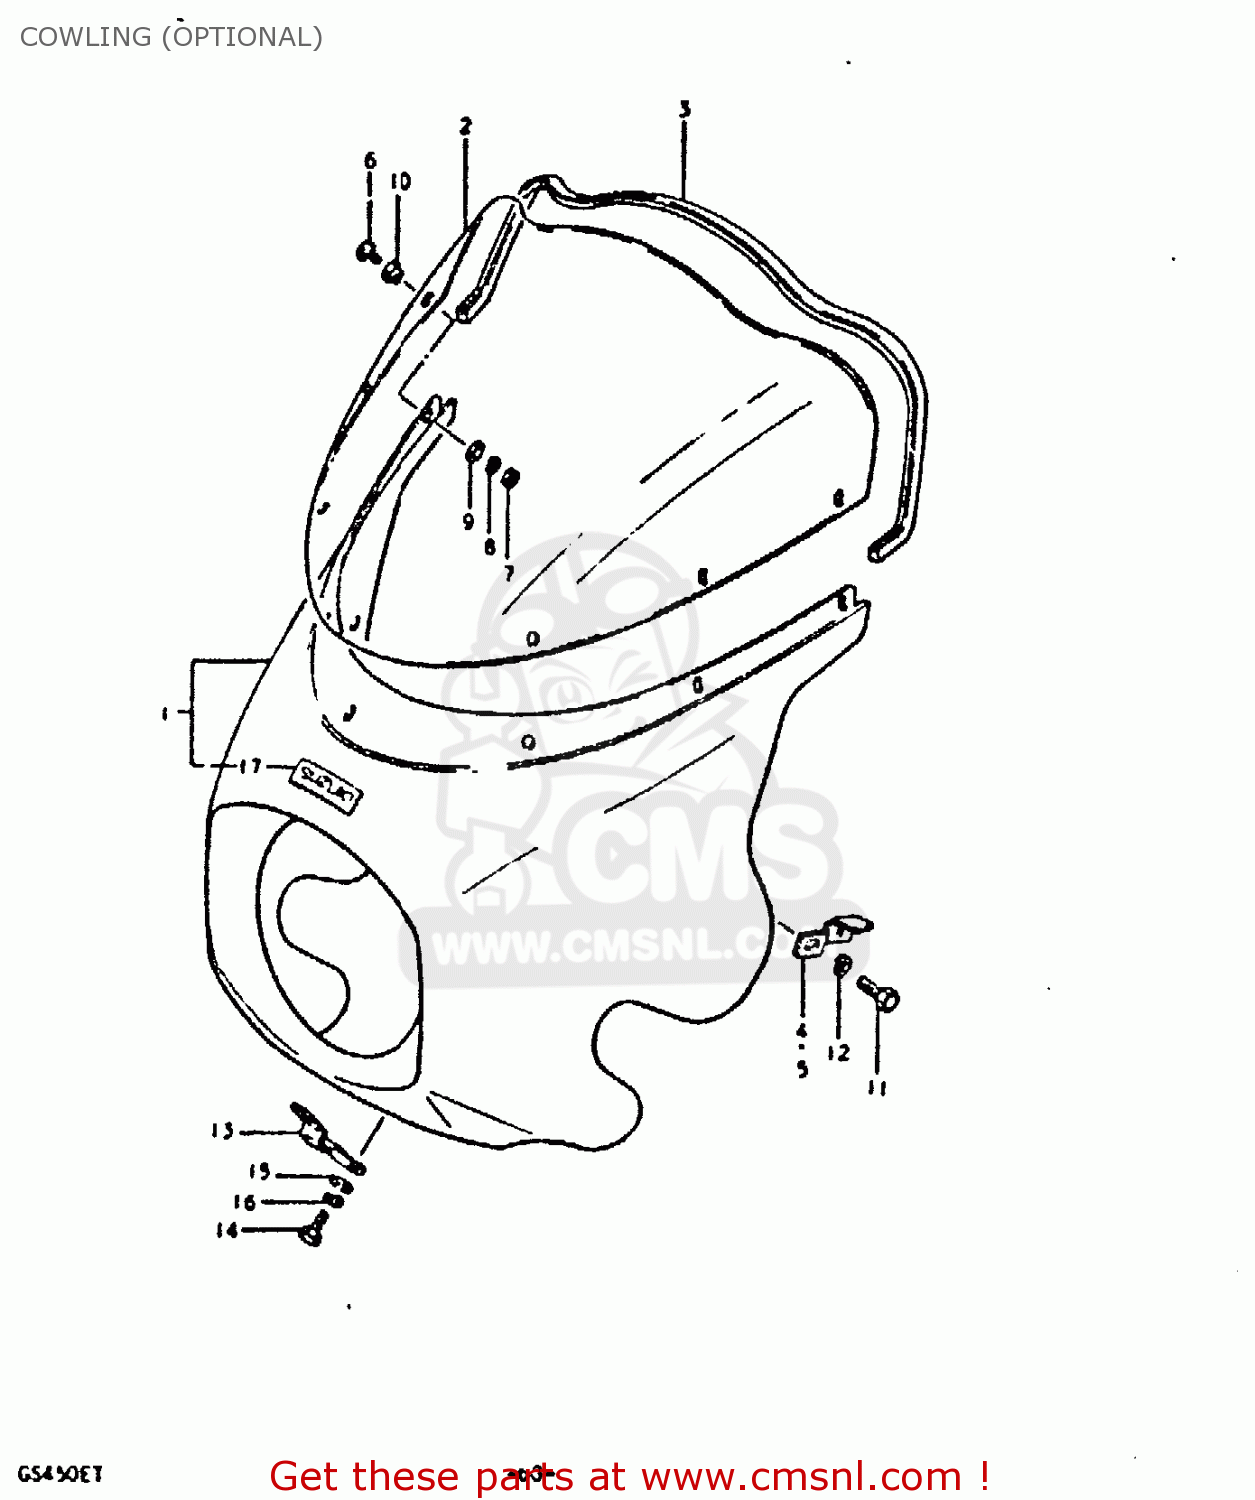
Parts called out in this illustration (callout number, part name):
1	COWLING, ASSY
2	WINDOW,COWLING
3	MOLDING,COWLING
4	BRACKET,COWLING,RIGHT
5	BRACKET, LH
6	SCREW
7	NUT
8	LOCK WASHER
9	WASHER
10	CUSHION
11	BOLT
12	LOCK WASHER
13	BRACKET,COWLING,LOWER
14	BOLT
15	WASHER
16	LOCK WASHER
17	EMBLEM
